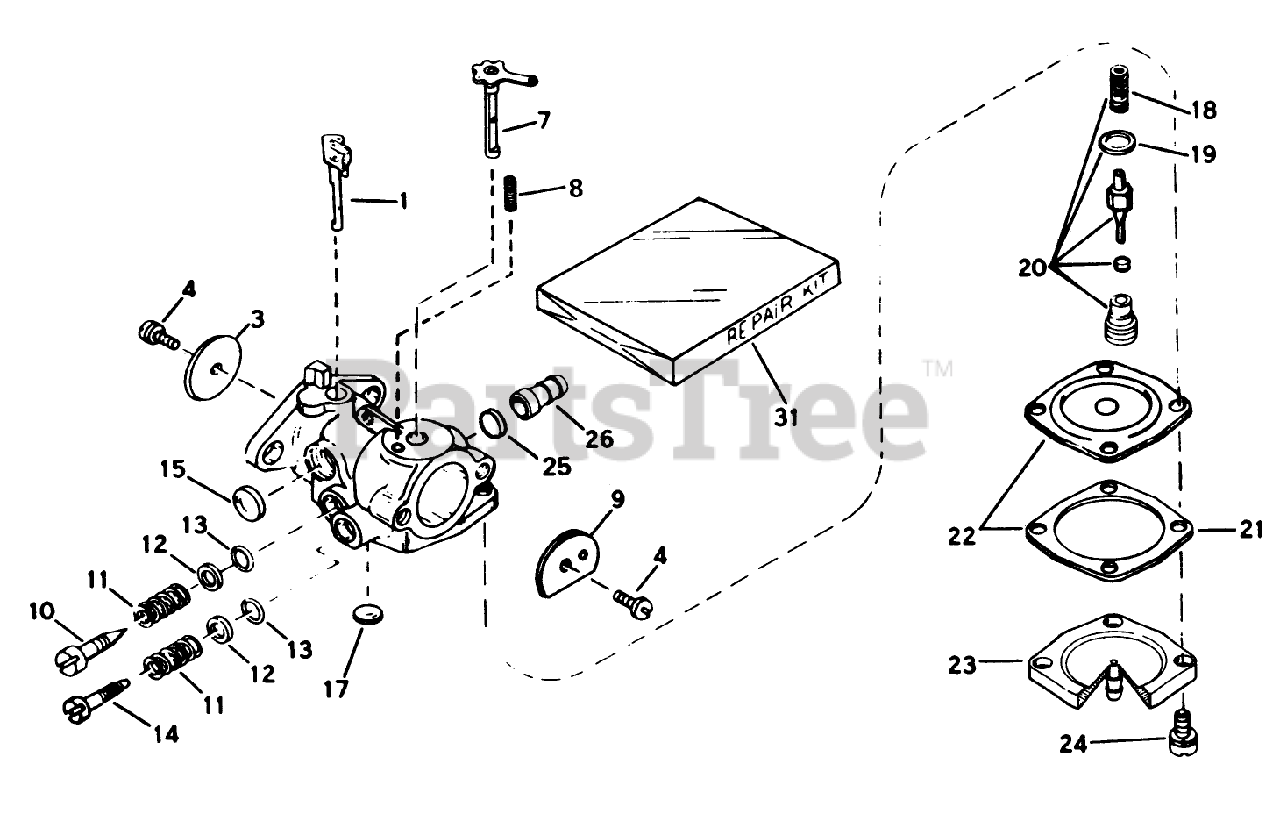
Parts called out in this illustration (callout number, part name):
1	Shaft/Lever-Throttle
3	Shutter-Throttle
4	Screw-Shutter
7	Shaft Lever Assembly
8	Spring-Positioning, Choke
10	Screw-Idle Adjustment
11	Spring
12	Washer
13	ORing
14	Screw Main Adjustment
15	Plug-Welch, Idle Mixture Well
17	Plug Welch
18	Spring-Valve
19	Gasket-Valve Seat
20	Inlet Needle, Seat, Spring Gasket Assy. (lncl. #1819)
21	Gasket-Diaphragm
22	Diaphragm Ass. (Incl. No. 21)
23	Cover-Diaphragm
24	Screw
26	Fitting-Fuel
31	Kit-Repair
